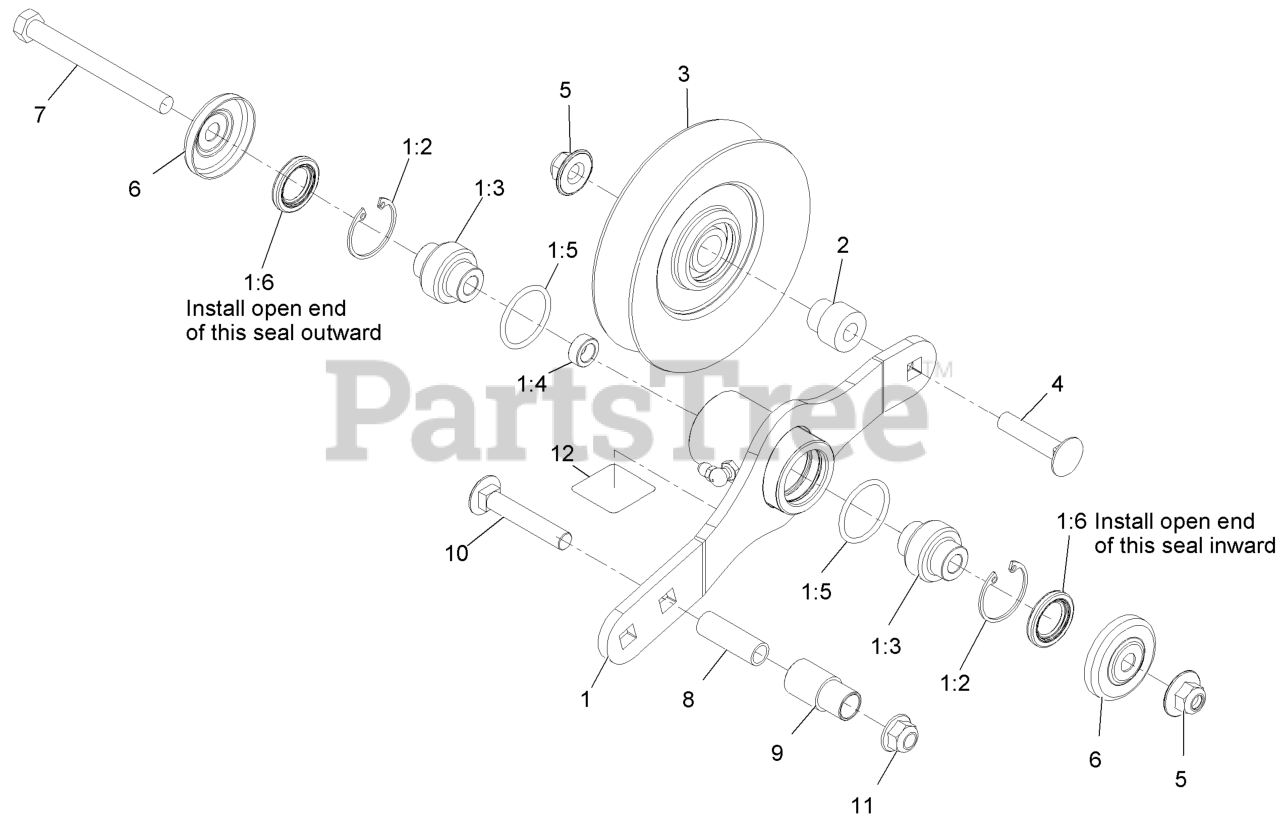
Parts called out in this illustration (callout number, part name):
1	ASM-Ttnr Arm W/Bearings
1:2	RING-SNAP
1:3	BEARING-SPHERICAL
1:6	SEAL-LIP, SINGLE
2	BUSHING-IDLER
3	PULLEY-IDLER
4	SCREW-CARR
5	Nut-Nyloc 3/8-16 Flg
6	GUARD-TOP
7	SCREW-HH
9	BUSHING,PLASTIC
10	Bolt-Carriage 3/8-16 X 2 1/4
11	NUT-HF, NI
12	DECAL,GREASE
